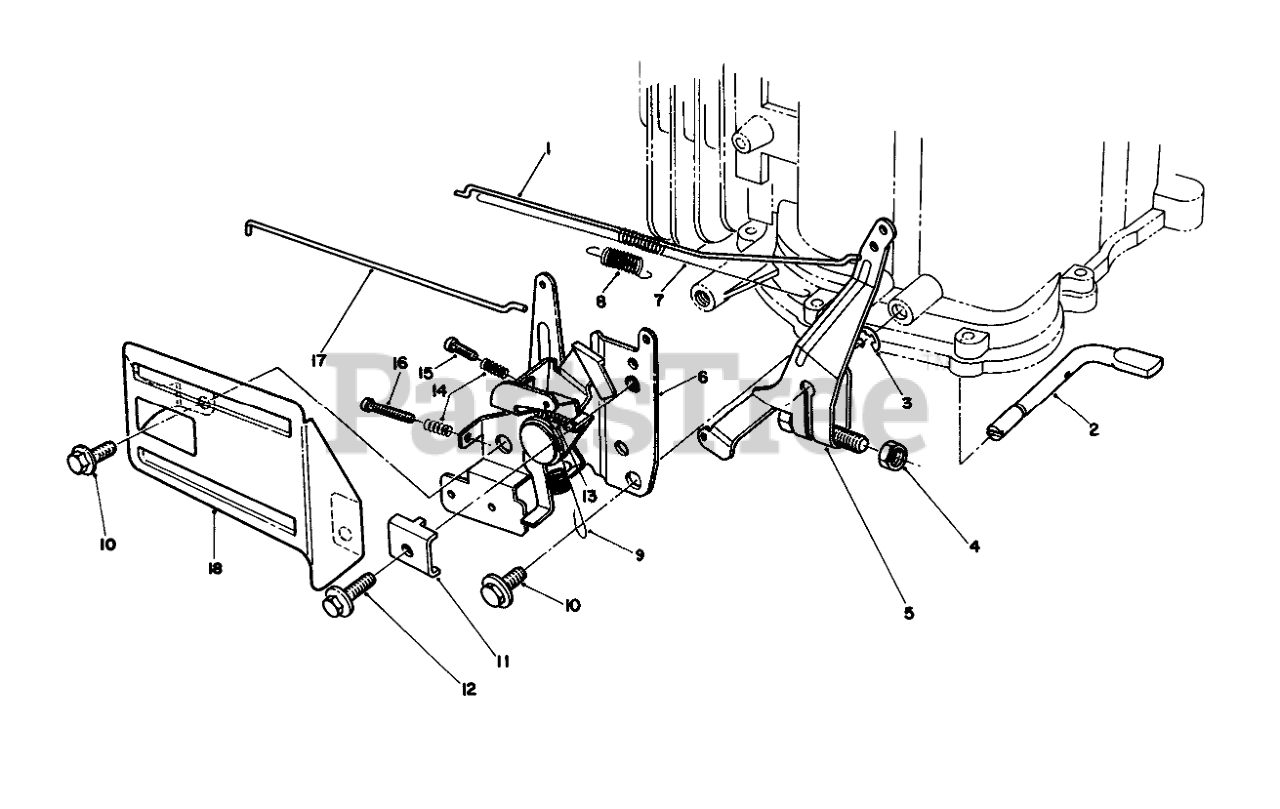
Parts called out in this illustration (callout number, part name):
1	Rod-Carburetor
2	SHAFT
3	E-RING
5	ARM ASM
6	THROTTLE
7	SPRING
8	SPRING
9	SPRING
11	CLAMP-CABLE
13	SPRING
14	SPRING
15	SCREW
16	SCREW
17	Rod-Choke
18	THROTTLE GUARD
